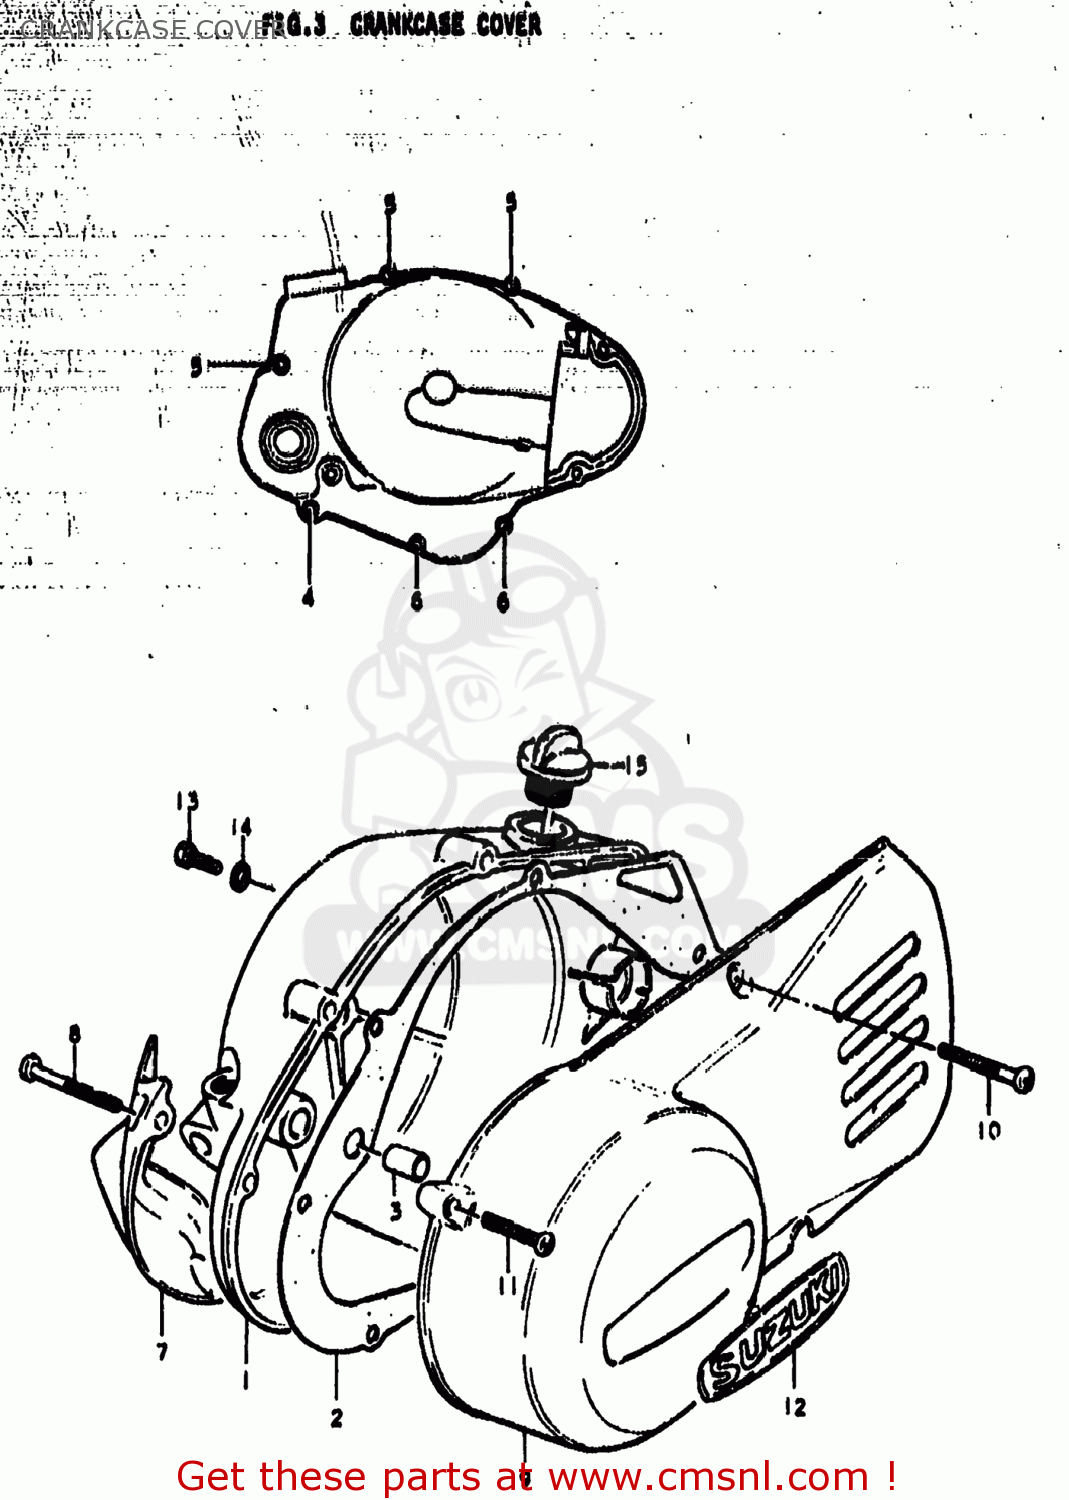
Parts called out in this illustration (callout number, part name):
1	COVER,CLUTCH
2	GASKET,CLUTCH COVER (MCA)
3	PIN
4	SCREW (6X45)
5	SCREW
6	SCREW
7	COVER,CLUTCH RELEASE A
8	SCREW
9	COVER,MAGNETO
10	SCREW
11	SCREW
12	EMBLEM,MAGNETO COVER
13	SCREW(6X10)
14	GASKET(6.2X11X1) (NAS)
15	PLUG
